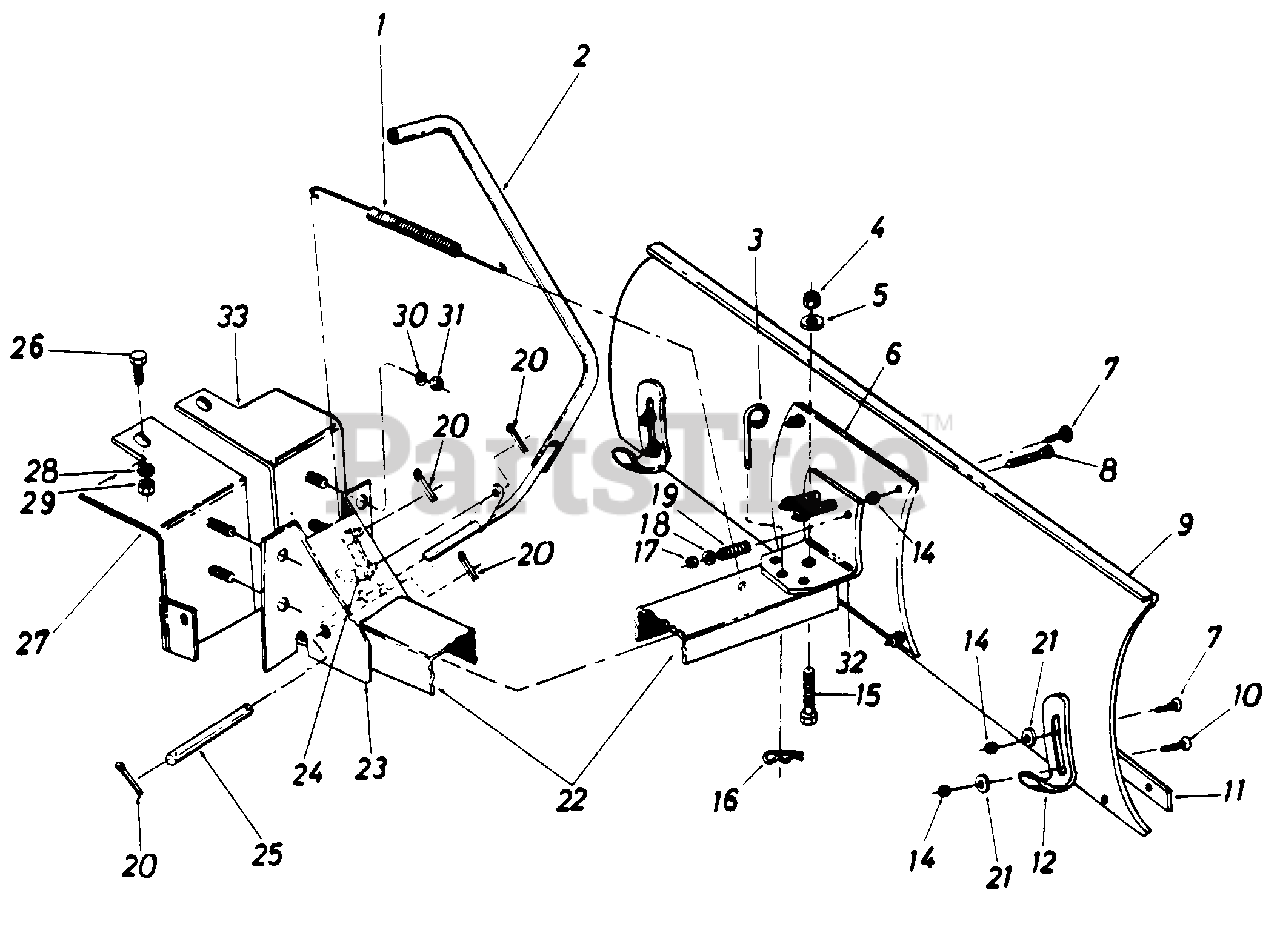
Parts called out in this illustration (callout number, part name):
1	Extension Spring
2	Litt Handle Ass'y.
3	Pivot Lock Pin
4	Hex Cent. L-Nut 1/2-13 Thd.
5	Fl-Wash. 17/32" I.D. x 1.25" Lg.
6	Rein1Orcement Plate
7	Carriage Bolt 5/16-18 x .75" Lg.
8	Hex Bolt 3/8-13 x 3.75" Lg. Grade 5
9	42" Blade
10	Carriage sOn 5/6-18 x 1" Lg.
11	42" Wear Plat
12	Shoe Skid
14	Hex Cent. L-Nut 5/16-18 Thd.
15	Hex Bolt 1/2-13 x 1.25" Lg.
16	Int. Cotter Pin
17	Hex Cent. L-Nut 3/8-16 Thd.
18	Fl-Wash. 3/8" I.D.
19	Compresion Spring
20	Cotter Pin 1/8" Dia. x l" Lg.
21	FI-Wash. 5/16" I.D.
22	Push Bar Channel
23	Pivot support Bracket
24	Lift Link
25	Channel Pivot Shaft
26	Hex Bolt 3/8-16 x 1" Lg. Grade 5
27	Support Bracket R.H.
28	L-Wash. 3/8" I.D.
29	Hex Nut 3/8-16 Thd.
30	L-Wash. 3/8" I.D.
31	Hex Jam Nut 3/8-15 Thd.
32	Support Bracket
33	Support Bracket L.H.
